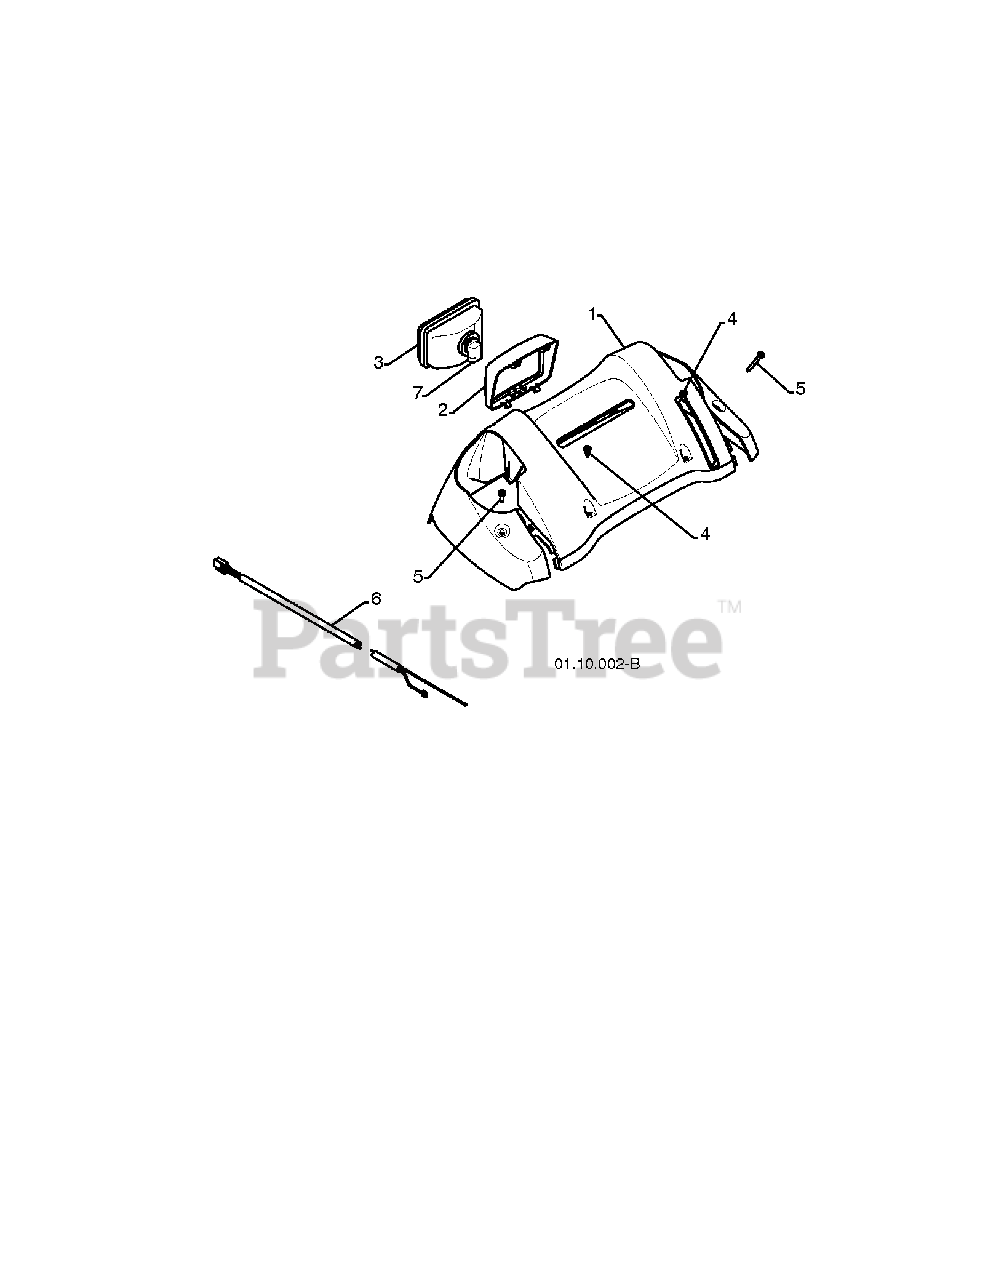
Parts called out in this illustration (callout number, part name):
1	PANEL.CONSOLE.HEADLIGHTS
2	BEZEL.HEADLIGHT.BLACK
3	HEADLIGHT, HALOGEN
4	SCREW, HEX HEAD, TAPPING
5	SCREW, HEX HD TAPPING #10-24 1
6	HARNESS.WIRE.HALOGEN
7	BULB.HEADLIGHT.HALOGEN.
